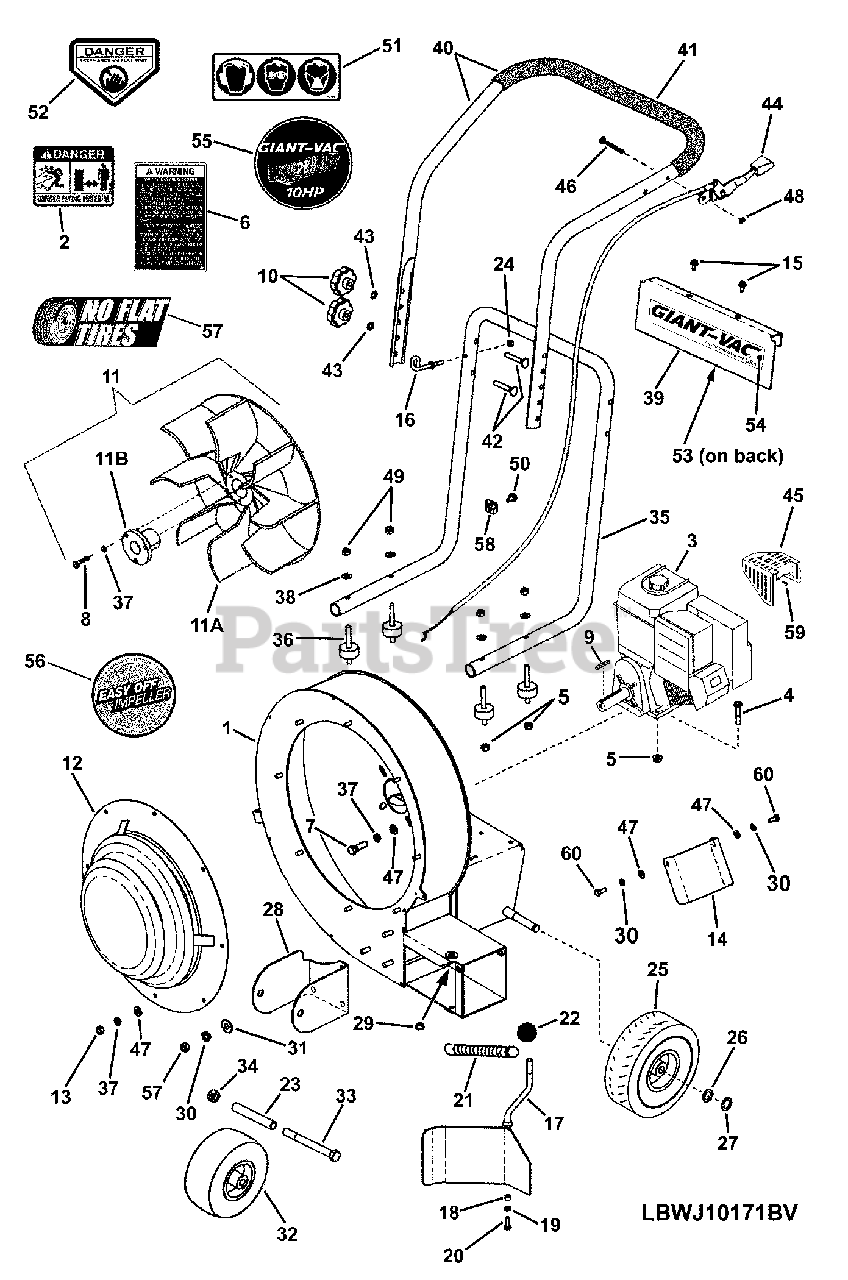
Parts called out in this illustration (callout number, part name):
1	WELDMENT, Housing- 10BWJ
2	DECAL, Thrown Objects, Large
4	SCREW, 5/16-18 x 1-1/2 Hex Head Cap, GR 5
5	NUT, 5/16-18 Hex Flange Lock, GR 5
6	DECAL, Warning- Leaf Blower
7	SCREW, 5/16-24 x 1" Hex Head Cap, GR 5
8	SCREW, 5/16-18 x 1-1/4", Hex Head Cap, GR 5
9	KEY, 1/4" Square x 2"
10	KNOB, Fluted- Folding Handles (5/16-18 thread)
11	ASSEMBLY, 17" 8 Curved Blade Impeller
11A	IMPELLER, Cast, 17" O.D.
11B	HUB, Taper-Lok, Type 1 (2.938 OAL)
12	WELDMENT, Intake Baffle- WJ- 17"
13	NUT, 5/16-18 Hex, GR 5 or B
14	DEFLECTOR, Side Air- WJ- 17"
15	SCREW, 5/16-18 x 5/8" Hex Washer Self-Tap
16	GUIDE, Rope (1/4-20 thread)
17	** WELDMENT, Door Discharge- WJ- 17"
18	BUSHING, Steel, .250 I.D. x .375 O.D. x .25 long
19	WASHER, 1/4" Split Lock
20	SCREW, 1/4-20 x 3/4" Hex Head Cap, GR 5
21	SPRING, Extension
22	KNOB, Ball Hand Lever- 3/8-16 Metal Insert
23	TUBE, .505/.515 I.D. x .625 O.D. x 4" long
24	NUT, 1/4-20 Hex Center Lock, GR 5 or B
25	ASSY., Wheel & Tire 410/350-4 "Flatfree"
26	WASHER, .64 x .99 x .05 Flat
27	RING, External Retaining (TRU1500-62)
28	BRACKET, Front Wheel, High Rise
29	BUSHING, Flanged .375 x .500 x .25 (.625 x .063 Flange)
30	WASHER, 3/8" Split Lock
31	WASHER, 3/8" Flat
32	ASSEMBLY, Tire & Wheel 9 x 350-4 "Flatfree"
33	BOLT, 1/2-13 x 5" Hex Head
34	NUT, 1/2-13 Hex Center Lock, GR 5 or B
35	HANDLE, Lower Folding- Wide- Blower
36	MOUNT, Vibration (5/16-18 thread- both ends)
37	WASHER, 5/16" Split Lock
38	WASHER, 5/16" Curved
39	DASH PANEL, Blower- Wide
40	ASSY, Upper Handle & Grip- Wide
41	GRIP, 1.0 x 21-1/2" Foam
42	BOLT, Curved Head Square Neck 5/16-18 x 2" GR 2
43	WASHER, 5/16" Internal Tooth Lock
44	THROTTLE CONTROL, Briggs
45	HEAT SHIELD, B&S 9 & 10 HP Intek Engines
46	SCREW, 1/4-20 x 2" Hex Head Cap, GR 5
47	WASHER, .34 x .69 x .08 Flat
48	NUT,1/4-20 Hex Nyloc
49	NUT, 5/16-18 Hex Nyloc
50	SCREW, Casing Clamp - B&S Intek Engine
51	DECAL, Personal Protection
52	DECAL, Danger, Cut Finger
53	DECAL, GIANT-VAC (Small)
54	DECAL, GIANT VAC
55	DECAL, 10 HP Whisper Jet
56	DECAL, Easy Off Impeller
57	DECAL, No Flat Tire
58	* CASING CLAMP, B&S Intek Engine
59	SCREW, #8-18 x 1/2" Hex Head Sheet Metal Screw
60	SCREW, 5/16-18 x 3/4" Hex Head Cap, GR 5
